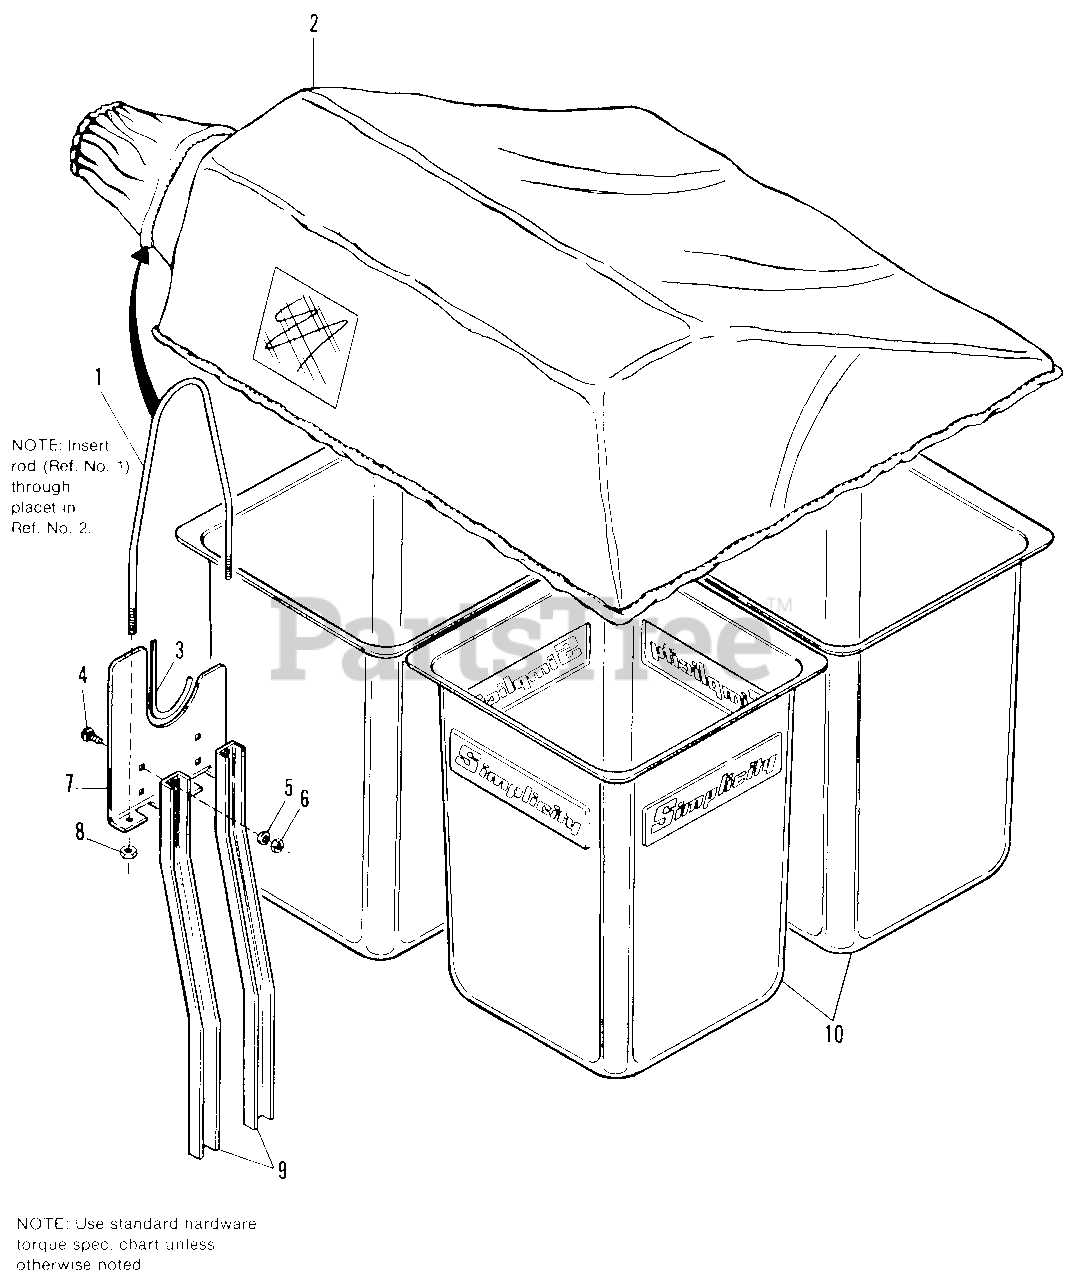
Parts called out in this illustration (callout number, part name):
1	CLAMP, Elbolw
4	CARRIAGE BOLT, 1/4-20 x 5/8
5	LOCKWASHER, Spring, 1/4
6	NUT, Hex, 1/4-20
7	BRACKET, Saddle
8	LOCKNUT, Hex, Full, 5/16-18
9	CHANNEL, Support
10	BASKET, Grass
